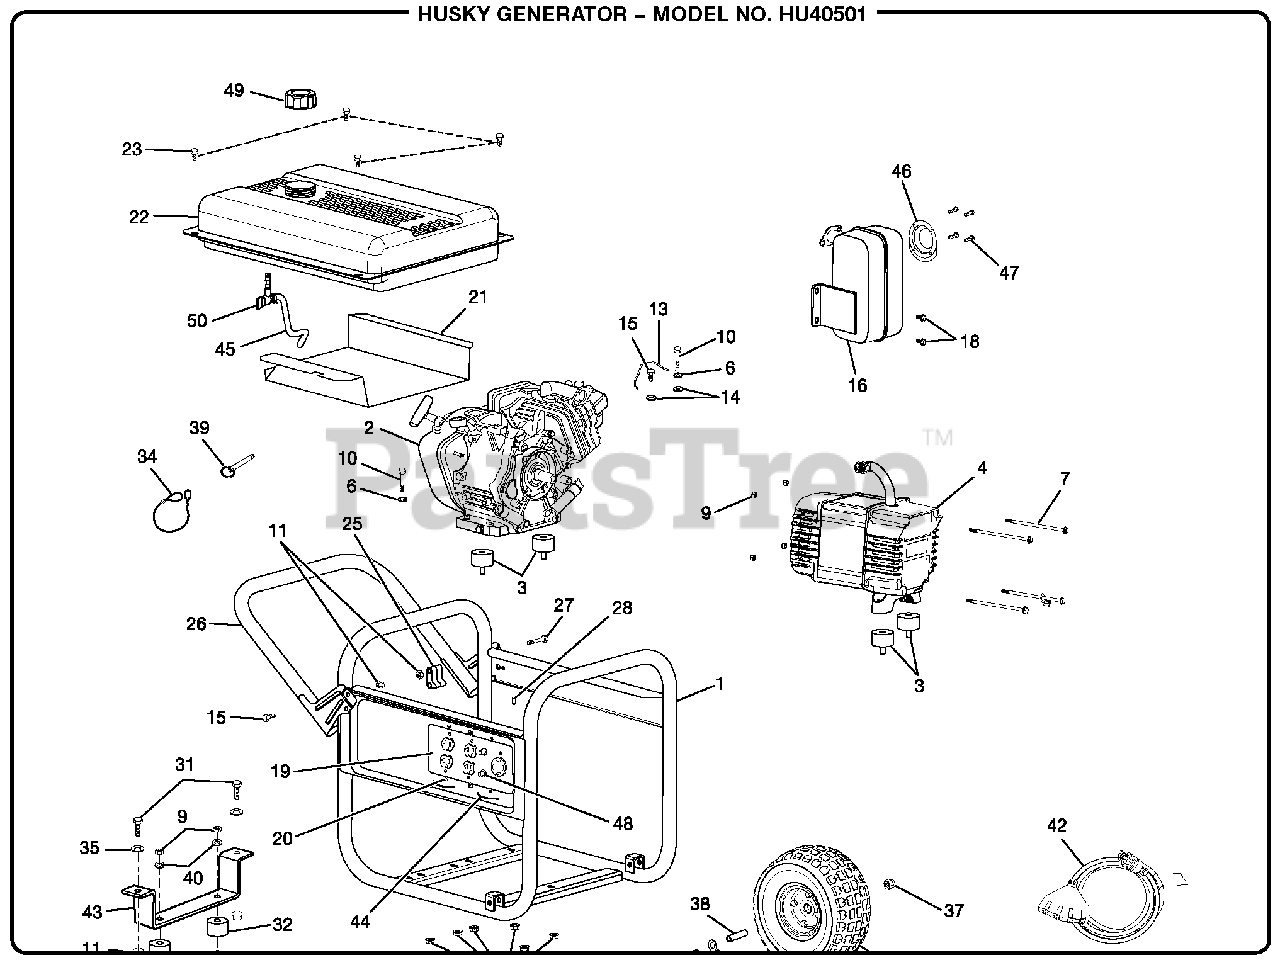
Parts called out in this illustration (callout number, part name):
1	Frame Assembly
2	Engine (Subaru OHC)
4	Bolt (3/8-16 x 3/4 in.)
5	Bolt (5/16-24 x 6-5/8 in., Hex Hd.)
6	Lock Washer (5/16 in.)
7	Bolt (1/4-20 x 6 in., Hex Hd.)
8	Ground Lug
9	Lock Nut (1/4-20)
10	Bolt (5/16-18 x 1-1/2 in.)
11	Lock Nut (5/16-18)
12	Flange Nut (5/16-18)
13	Ground Wire Assembly
14	Washer (5/16 in.) External Star
15	Bolt (5/16-18 x 3/4 in., Hex. Hd.)
18	Bolt (5/16-24 x 5/8 in.)
19	Wire Panel
20	Screw (6-19 x 1/2 in.)
21	Heat Shield
22	Fuel Tank Assembly
23	Screw (#10 x 1 in.)
24	Nut (8 mm)
25	Handle Lock Bracket
27	Bolt (5/16-18 x 1-3/4 in.)
28	Rubber Cap
29	Bolt (5/16-24 x 5/8 in.)
31	Bolt (5/16-18 x 1 in.)
32	Rubber Foot
33	Washer (3/8 in.)
35	Washer (5/16 in.)
36	Bolt (3/8-16 x 4-1/4 in.)
37	Lock Nut (3/8-16)
38	Spacer (.38 ID)
39	Handle Lock Pin
41	Ground Wire Assembly
42	Extension Cord (25 foot, 20 amp)
43	Bolt (1/4-20 x 1-1/2 in.)
44	Washer (1/4 in.)
45	Frame Support
46	Cord Retainer
47	Fuel Line Assembly
48	Spark Arrester Screen
49	Screw (8-32 x 3/8 in.)
50	Circuit Breaker (25 amp)
52	Fuel Shut Off with Filter
